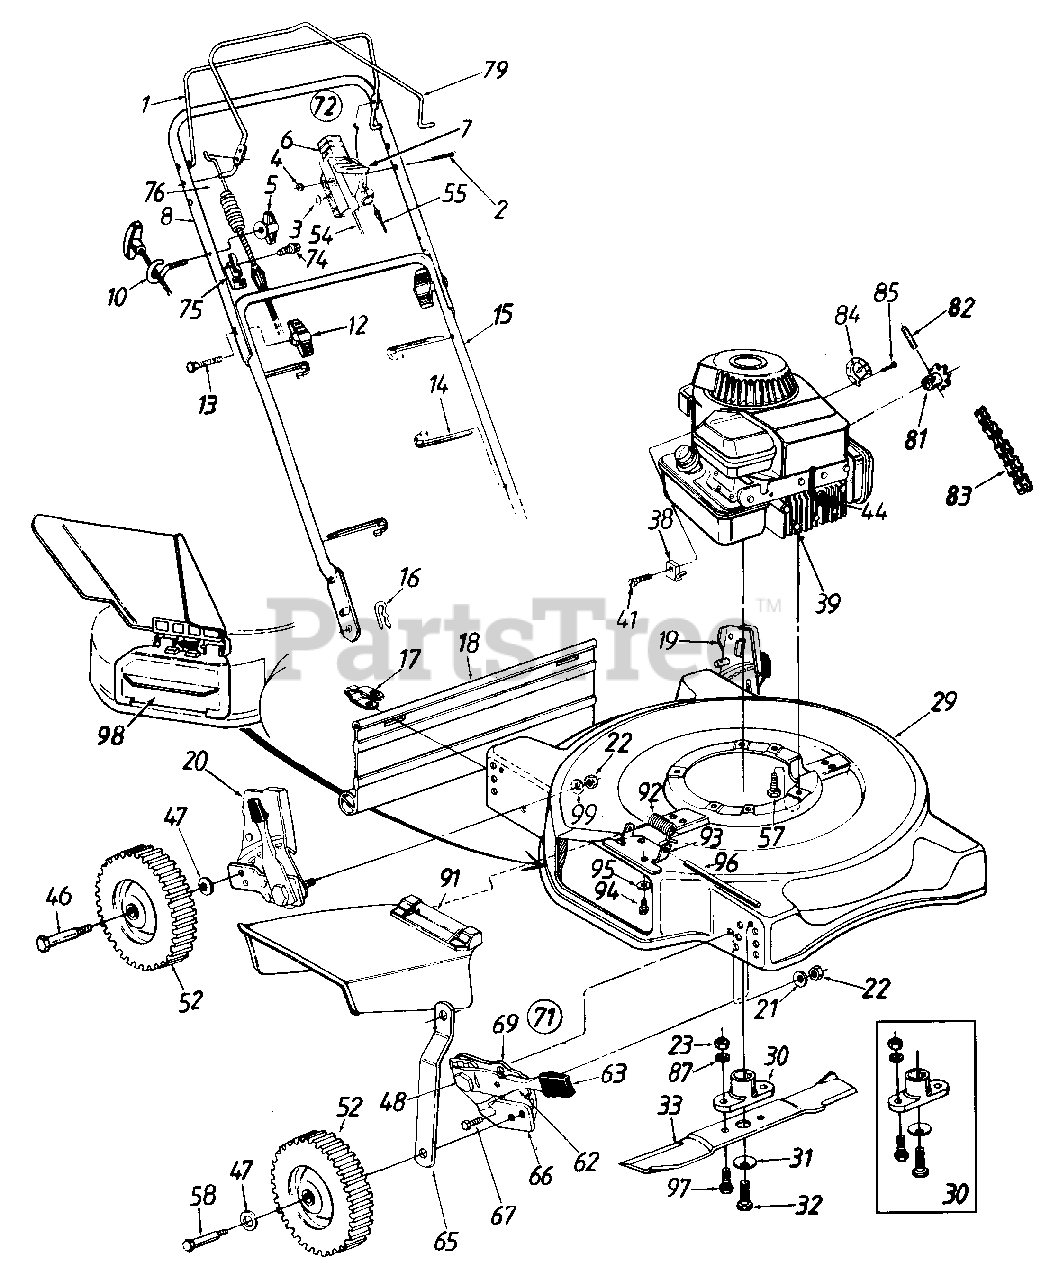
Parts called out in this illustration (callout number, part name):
2	Oval C-Sunk Mach. Scr.
3	Spr. Wash. .66" I.D.
4	Hex L-Nut 1/4-20 Thd.
5	Handle Knob 1/4-20 Thd.
6	Throttle Body
7	Throttle Lever
12	Hand Knob
13	Curved Hd. Bolt 5/16-18 x 2" Lg.
14	Cable Tie
16	Hairpin Cotter
17	Hinge Clip
18	Rear Flap
22	Hex Nut 3/8-16 Thd.
23	Hex Nut 3/8-24 Thd.
31	Bell-Wash. .39" I.D.
32	Hex Bolt 3/8-24 x 1.5" Lg.
33	22" Blade
38	Cable Clamp
39	Engine
41	Hex Wash. Hd. Scr. #10-32 x
44	Spark Plug Boot
46	Front Axle Bolt
47	Bell-Wash. .400" I.D. x .88"
48	Shld. Bolt .50" Dia. x .357"
52	Front Wheel Ass'y. Comp.
54	Throttle Control Wire - 51"
55	Control Cable - 51"
57	Hex L-Wash. Hd. Scr. 3/8-16 x 1.0" Lg.
58	Rear Axle Bolt
62	Spring Lever
63	Spring Lever Knob
67	Hex L-Wash. Hd. AB-Tap Scr. 1/4 x .62" Lg.
69	Index Plate
72	Throttle Box Comp.
74	Hex Wash. AB-Tap Scr. 5/16 x .75" Lg.
75	Cable Brkt.
76	Clutch Cable w/Spring - 47"
82	Spring Pin Spir. 3/16" Dia. x 1" Lg.
83	#48 Chain 1/2" Pitch 50 Links (Endless)
84	Exhaust Deflector
85	Hex AB-Tab Scr. #8 x .5" Lg.
87	L-Wash. 3/8" I.D.
91	Chute Deflector Ass'y.
92	Torsion Spring
93	Adapter Plate
94	Hex Self-Tap Scr. 1/4-20 x .5" Lg.
95	Bell-Wash. 1/4" I.D.
96	Hinge Pin
97	Hex Bolt 3/8-24 x 1" Lg.
98	Mulching Plug
99	Bell-Wash. .39" I.D. x 1.38" O.D.
